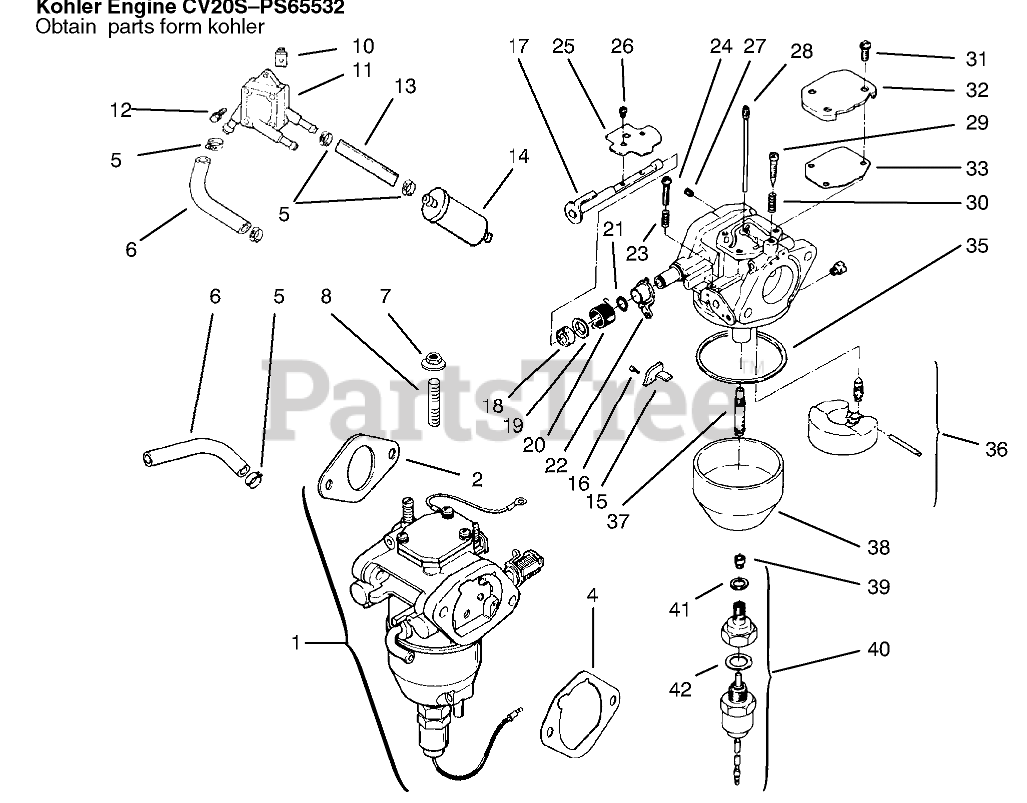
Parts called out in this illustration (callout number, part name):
1	Kit-Carb INC2/4/15-42
2	Kit-Carburetor
4	Gasket-A/C Base
5	Clamp
6	Line-Fuel
9	Line-Fuel 12"
10	Nut
11	Pump-Fuel
12	Screw
13	Line-Fuel
14	Filter-Fuel
15	Bracket-Throttle Stop
16	Screw
17	Shaft-Choke
18	Washer
19	Collar-Coke
20	Spring-Choke Return
21	Ring-Choke Lever
22	Lever-Choke
23	Sprin-Throttle Screw
24	Screw-Throttle Adjust
25	Valve-Choke
26	Screw
27	Jet-Air Bleed
28	Jet-Slow
29	Screw
30	Spring-idler Screw
31	Screw
32	Cover-Passage
33	Gasket-PassageCover
35	Gasket-FloatChamber
36	Kit-Float Repair
37	Nozzle-Main
38	Chamber-Float
39	Jet-Main
40	Kit-Solenoid INC41-42
41	Gasket-ChamberScrew
42	Gasket-Solenoid
